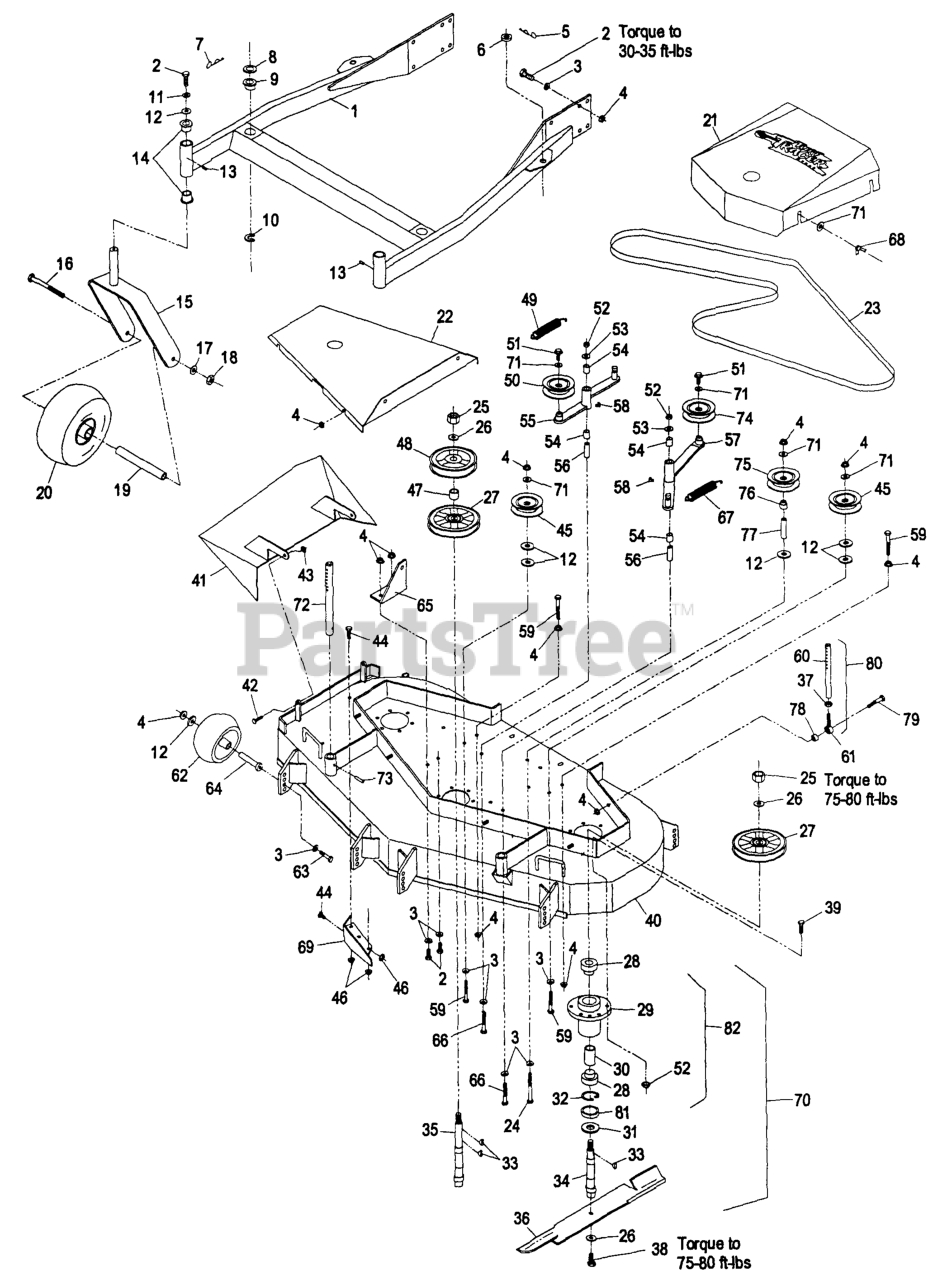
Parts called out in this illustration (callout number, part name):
5	PIN,HAIR COTTER
8	SPACER-DECK SUPPORT
9	BUSHING-DECK
12	WASHER
14	BEARING-FLANGED
23	BELT,BLADE DRIVE
26	WASHER-SPRING
27	SHEAVE,BLADE DRIVE
28	BEARING
30	SPACER-BEARING
31	GUARD-BEARING, BOTTOM
34	SHAFT,SPINDLE SHORT
35	SHAFT,SPINDLE LONG
41	WLD,CHUTE DISCHARGE
45	IDLER,PULLEY
47	SPACER-TUBE
48	SHEAVE,MOWER DRIVE
49	SPRING-EXTENSION
50	IDLER,PULLEY
54	SLEEVE-BEARING
55	ASM,IDLER ARM
56	BUSHING-PIVOT, IDLER
57	ASM,IDLER ARM
60	LINK, DECK SUPPORT
61	BALLJOINT
62	ROLLER-SCALP, ANTI
64	BUSHING-ROLLER
65	BRACKET,SPRING ANCHOR
66	SCREW-HH
67	SPRING-EXTENSION
68	NUT-WING
69	WLD,BAFFLE DISCHARGE
70	CUTTER HOUSING ASSY,CEN
72	ROD,DECK SUPPORT
74	PULLEY-IDLER
75	PULLEY-IDLER
76	BUSHING,IDLER
77	SPACER-FENDER
81	SPACER-PULLEY/BEARING
